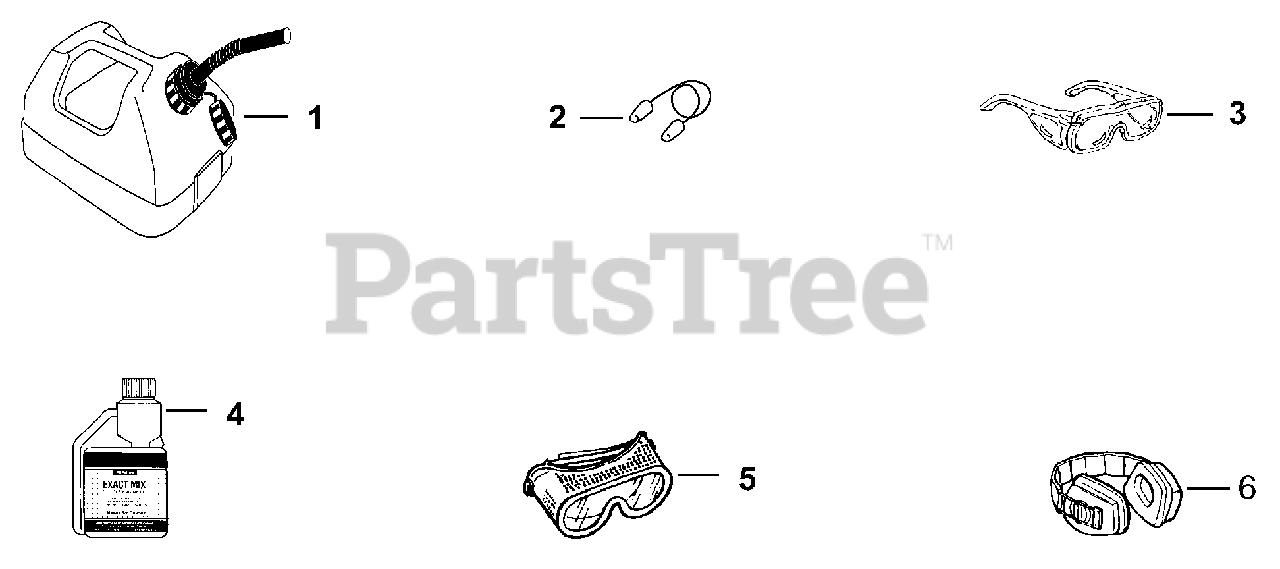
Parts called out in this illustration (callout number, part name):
1	GAS CAN 1 1/4 Gallon
2	EAR PLUGS
3	SAFETY GLASSES-Clear
4	EXACT MIX (TM) Oil - 1 pint (50:1)
5	GOGGLES
6	EAR PROTECTORS
